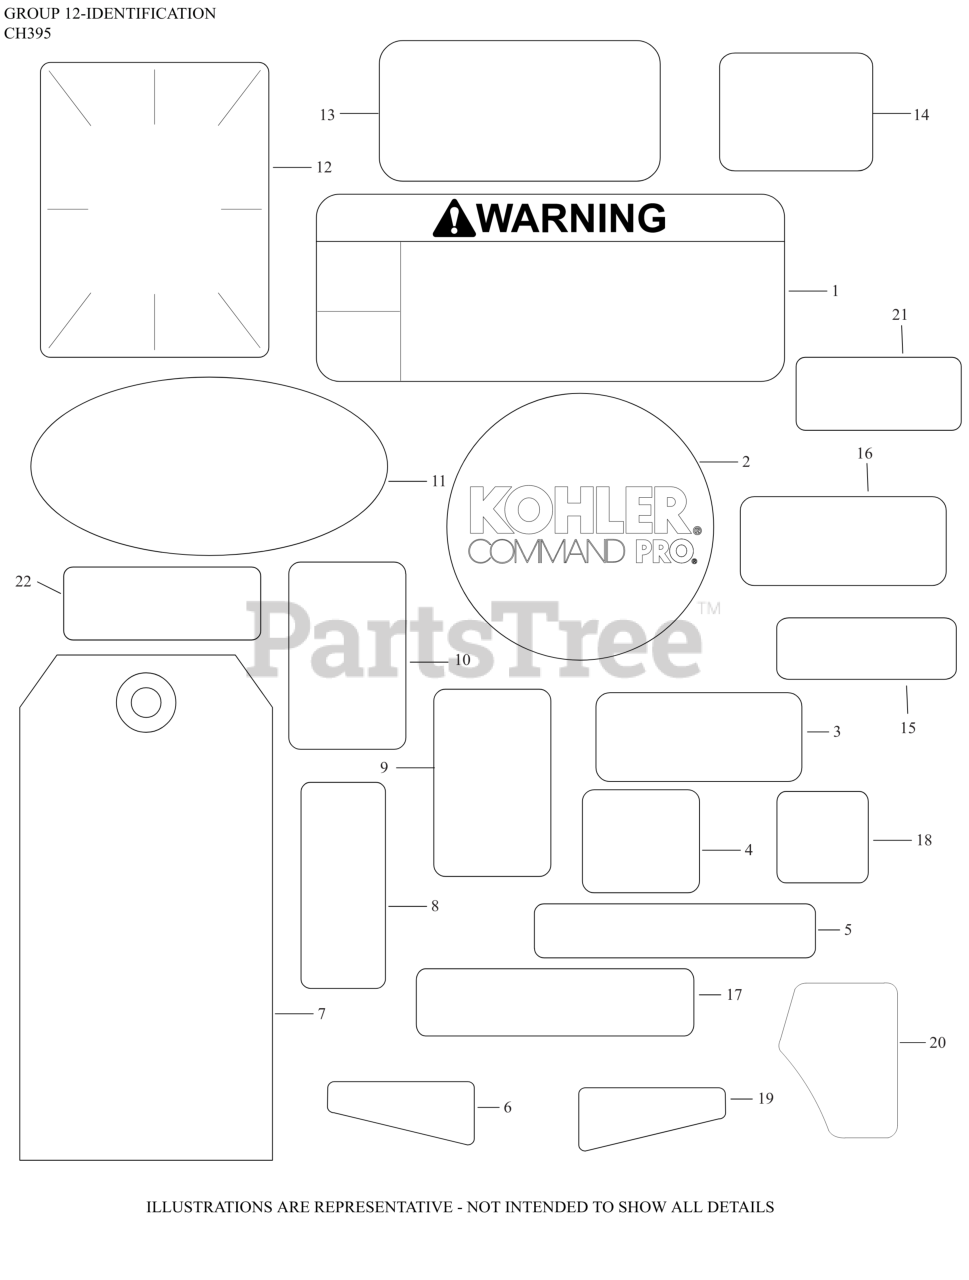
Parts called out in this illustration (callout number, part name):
1	DECAL, WARNING
2	LABEL, RECOIL 75MM
3	LABEL, CANADIAN COMPLIANCE
4	DECAL, BASE ARROW
5	DECAL, THROTTLE
6	DECAL, 9.5 HP/277cc/CH395
8	DECAL, FUEL/CHOKE - ON/OFF
9	DECAL, SUN
10	DECAL, SNOW FLAKE
11	DECAL, QUAD CLEAN SILVER
12	LABEL, CLEAR LAMINATION
13	LABEL, MAINTENANCE (CKY)
16	DECAL, ETHANOL WARNING
